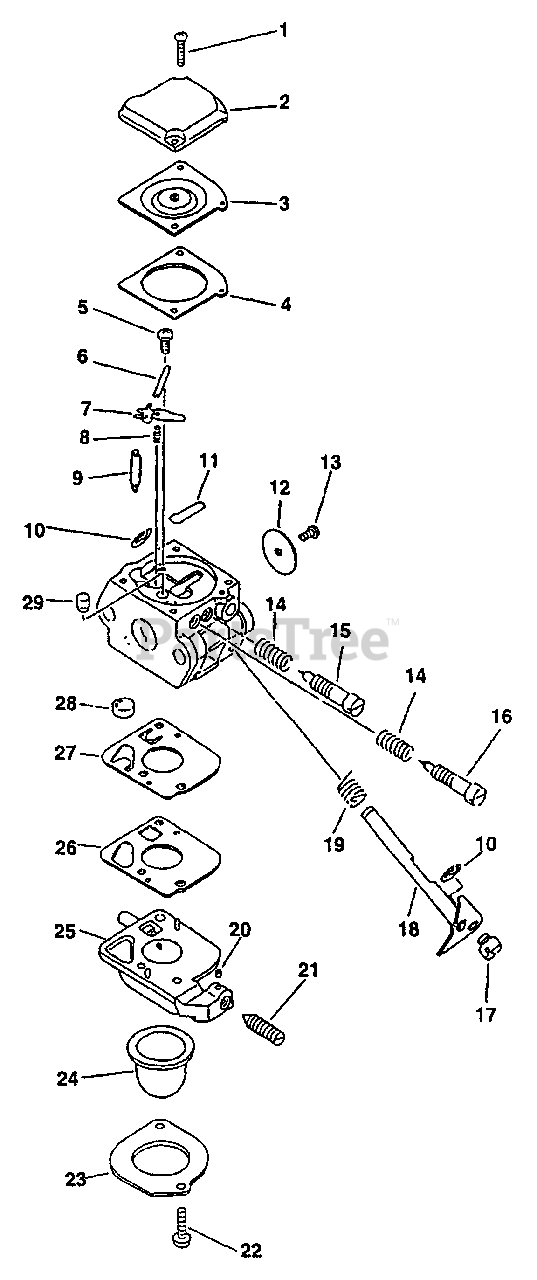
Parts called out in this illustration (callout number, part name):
2	COVER, DIAPHRAGM
3	DIAPHRAGM
4	GASKET, METERING
6	PIN
7	LEVER, METERING
8	SPRING
9	VALVE, NEEDLE
11	PLUG, WELCH
12	VALVE, THROTTLE
13	SCREW 3×4.5
14	SPRING, NEEDLE
15	NEEDLE, IDLE
16	NEEDLE, HIGH SPEED
18	SHAFT, THROTTLE
19	SPRING, THROTTLE RETURN
20	PIECE, FRICTION
21	SCREW, IDLE ADJUST
23	RETAINER
24	BULB, PURGE
25	BODY ASSY, PURGE
28	STRAINER
29	NOZZLE, CHECK VALVE
